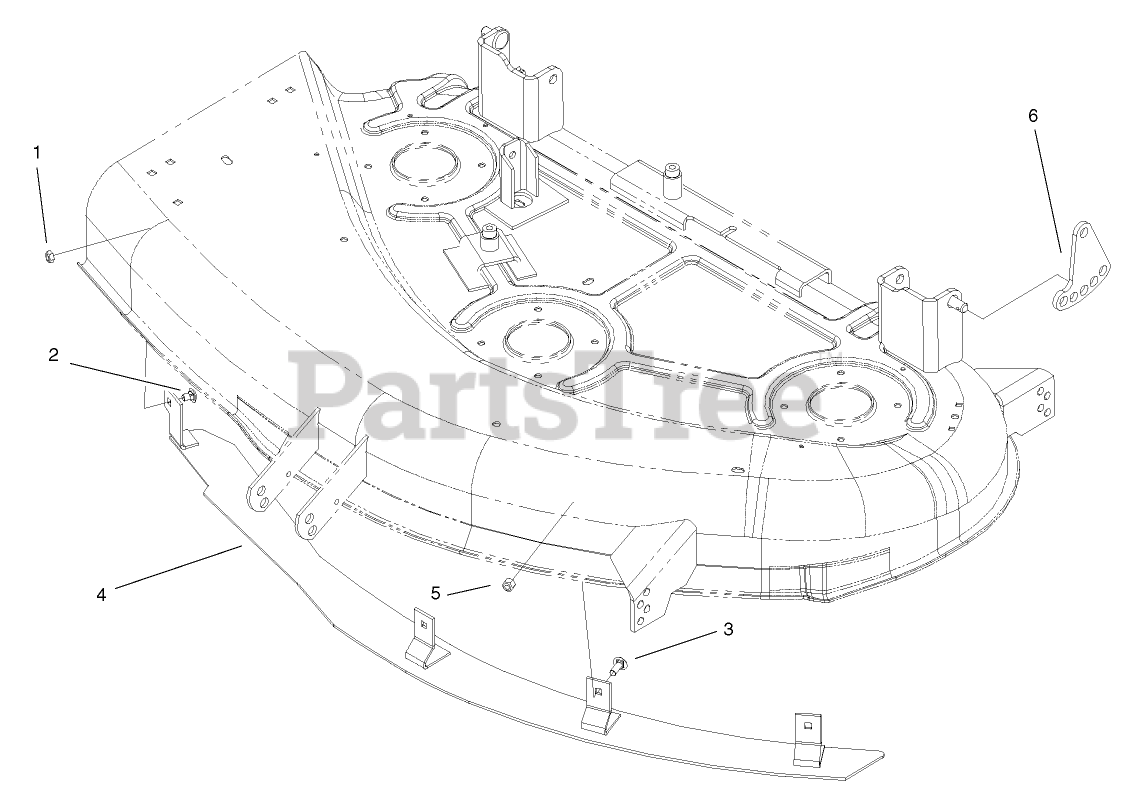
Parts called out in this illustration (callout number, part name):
1	NUT-LOCK, NI
2	BOLT-CARR
3	SCREW-CARR
5	NUT-LOCK, NI
6	LINK-HOC, ADJUSTING
